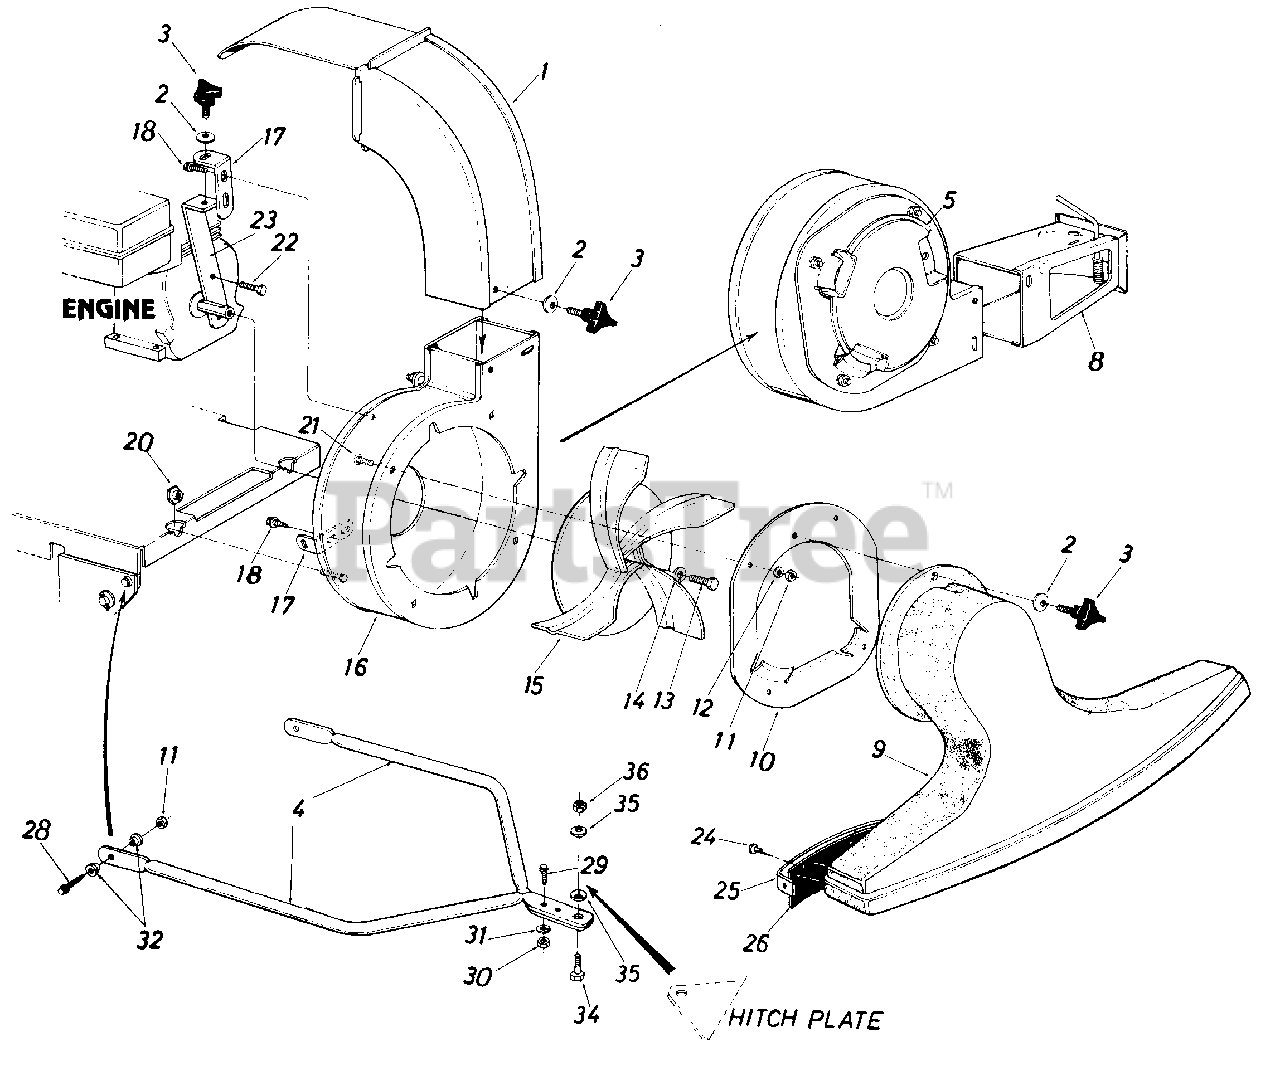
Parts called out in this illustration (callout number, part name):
3	3-Arm Thumb Scr. 5/16-18 x .75" Lg.
10	Nozzle Plate Ass'y.
11	Hex Nut 5/16-18 Thd.*
12	L.-Wash. 5/16" I.D.
13	Hex Bolt 3/8-24 x 1.25" Lg.*
14	L.-Wash. 3/8" I.D. H.D.
15	Air Vane Plate Ass'y.
16	Blower Housing Complete
20	Hex Shoulder Nut .50 I.D.
21	Carriage Bolt 5/16-18 x .62" Lg.*
22	Hex Locking Bolt 5/16-24 x .75" Lg.
28	Hex Bolt 5/16-18 x 1.00" Lg.*
29	Truss Mach. Scr. 1/4-20 x .75" Lg.*
30	Hex Nut 1/4-20 Thd.*
31	L.-Wash. 1/4" I.D.*
32	Shoulder Spacer
34	Shld. Bolt .496 Dia.
35	Belleville Wash. .39 I.D. x 1.12 O.D.
36	Hex Jam L-Nut 3/8-16 Thd.
